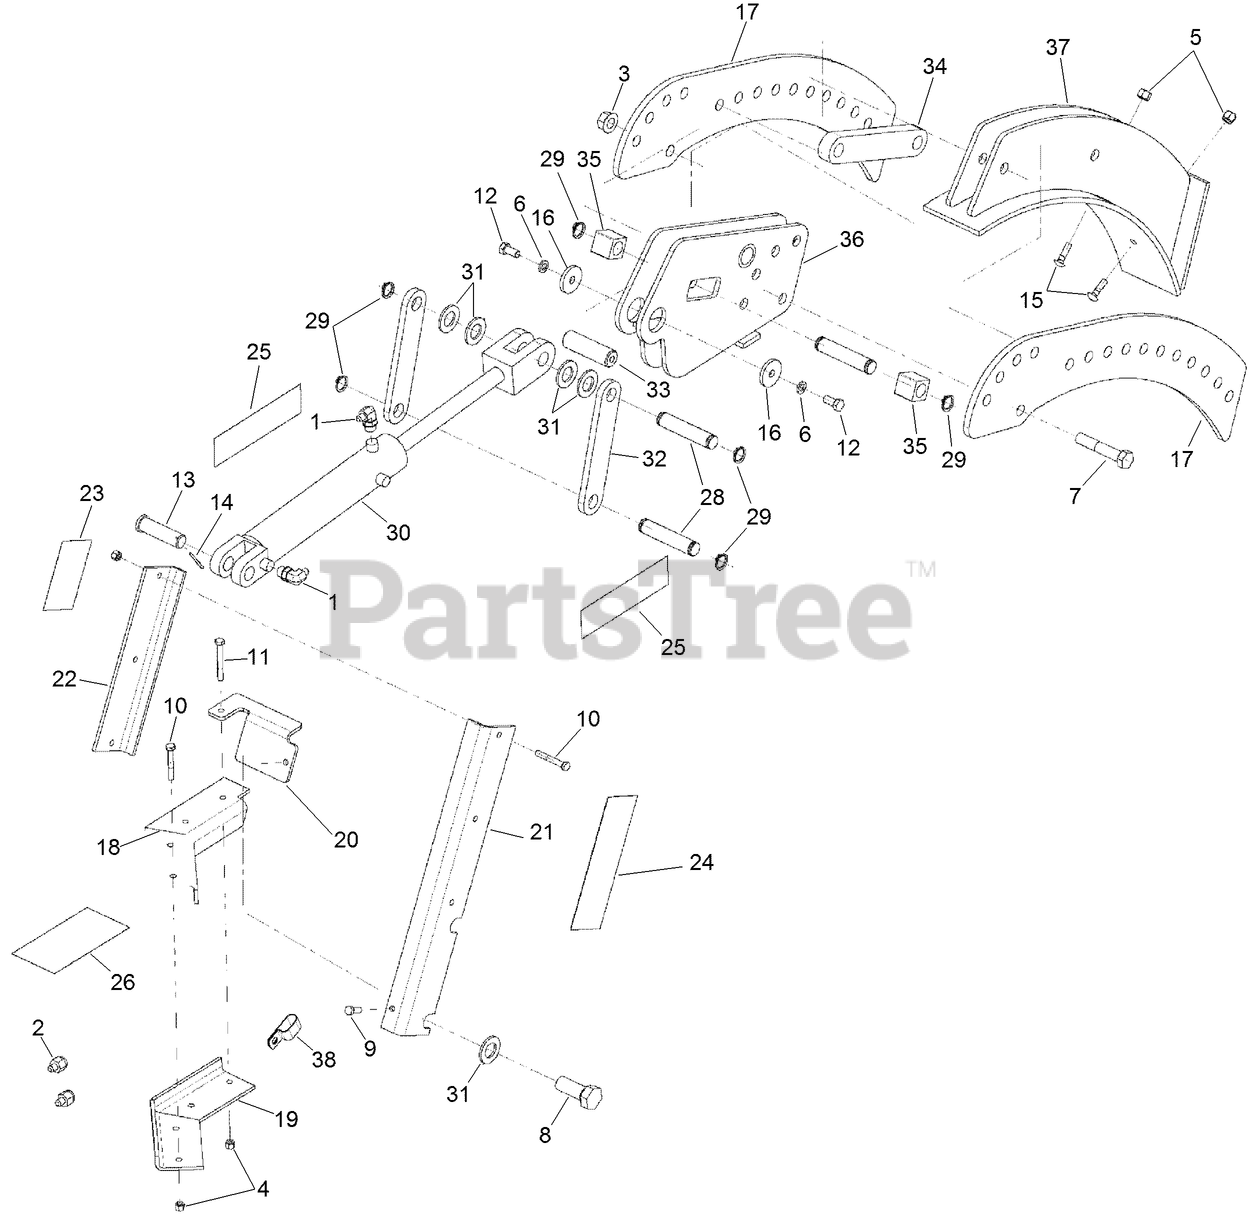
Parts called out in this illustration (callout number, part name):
1	ELBOW-90 Adj 37FL, 3/8 x 1/2 Tube
3	NUT-HEX FLANGE
4	NUT-HEX
5	NUT-HEX
6	WASHER - Spring Lock Reg .500 in PHC
9	SCREW-HH
10	SCREW-HH
11	BOLT-hex, 3/8 NC x 3 inch
12	SCREW-HH
13	PIN-clevis, 1 x 3-1/2 inch, hardened
14	PIN-cotter, 5/32 x 1-3/4 inch
15	BOLT - Round Hd .375 x 1.50 GR5 ZND
16	WASHER-FLAT
17	PLATE-CRUMBER CONNECTOR
18	ANGLE WELDMENT - Conduit, Upper
19	ANGLE WELDMENT - Conduit, Lower
20	ANGLE - Tie
21	ANGLE - Conduit (long)
22	ANGLE - Conduit (short)
23	DECAL-DANGER, ENTANGLE HAZZARD
24	DECAL-Danger, Trencher Entanglement Hazard
25	DECAL-Danger, Entanglement Hazard
26	DECAL - Hyd Crumber Oper Instructions
28	PIN-CYLINDER, ROD
29	RING - Snap
30	ASSEMBLY - Cylinder
32	LINK - Crumber, Straight
33	PIN-PIVOT, CRUMBER PIVOT
34	LINK-CRUMBER PUSH
35	BLOCK-SLIDE - SQ. BAR
36	PIVOT WELDMENT - Crumber
37	SHOE WELDMENT - Crumber
38	CLAMP-DOUBLE
